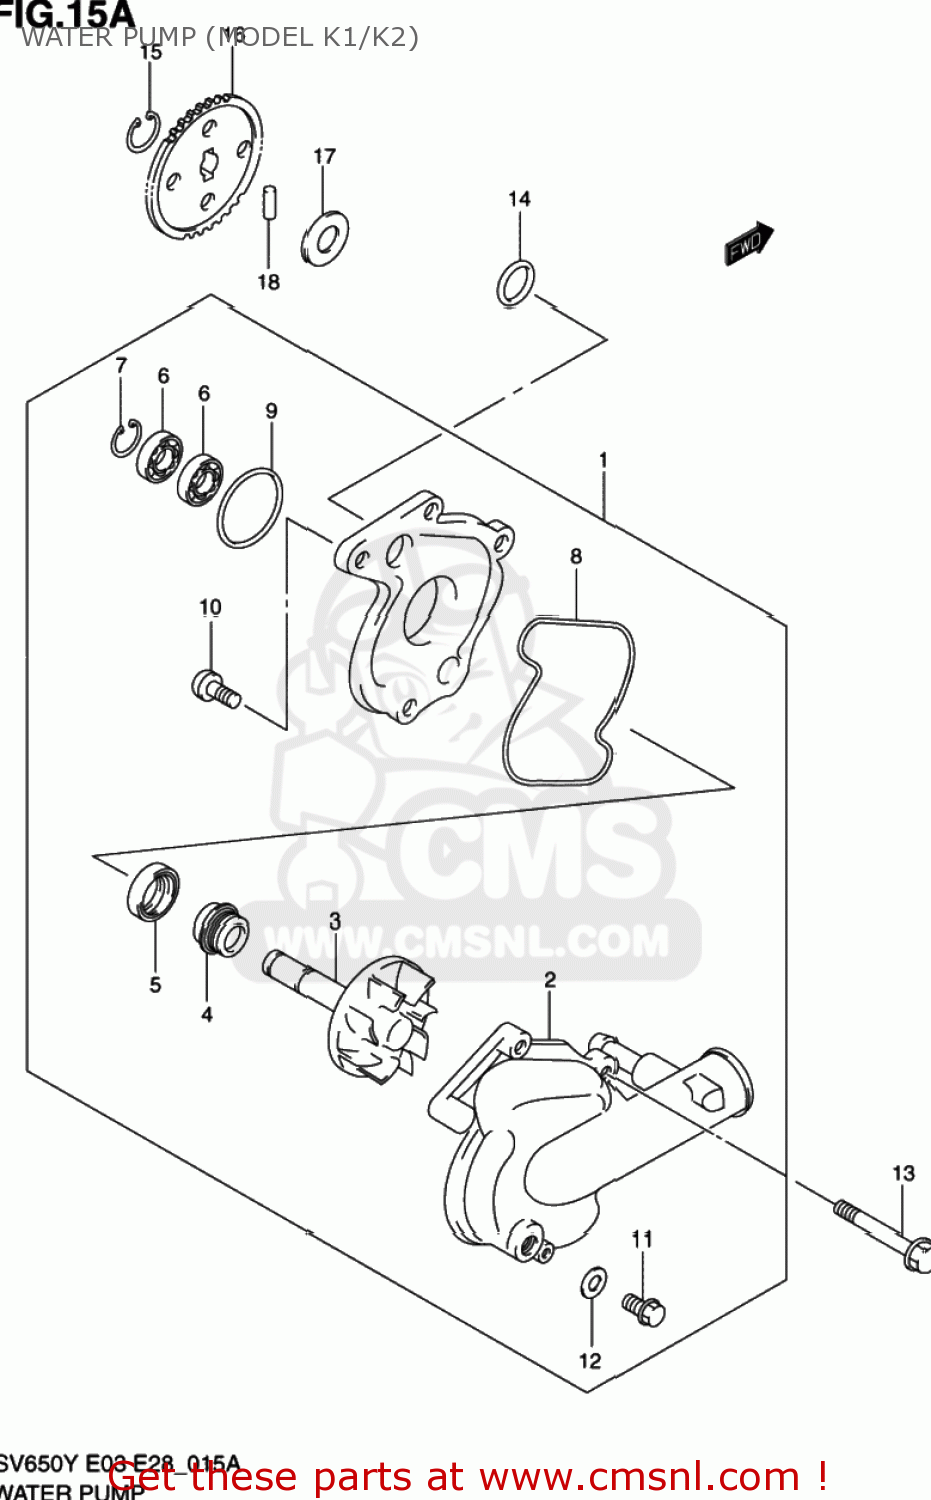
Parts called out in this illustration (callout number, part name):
1	WATERPOMP SET
2	CASE,WATER PUMP
3	IMPELLER/SHAFT
4	SEAL,MECHANICAL
5	SEAL,OIL(10X21X5)
6	BEARING
7	E RING
8	O RING
9	O RING,WATER PUMP HOLDER
10	SCREW 6X16
11	BOLT,DRAIN
12	GASKET 8.2X14X1 (NAS)
13	BOLT(6X50)
14	O RING(D:2.4,ID:21.8)
15	CIRCLIP,10MM
16	GEAR,WATER PUMP DRIVEN
17	SHIM(10X18X0.5)
18	ROLLER(4X13.8)
